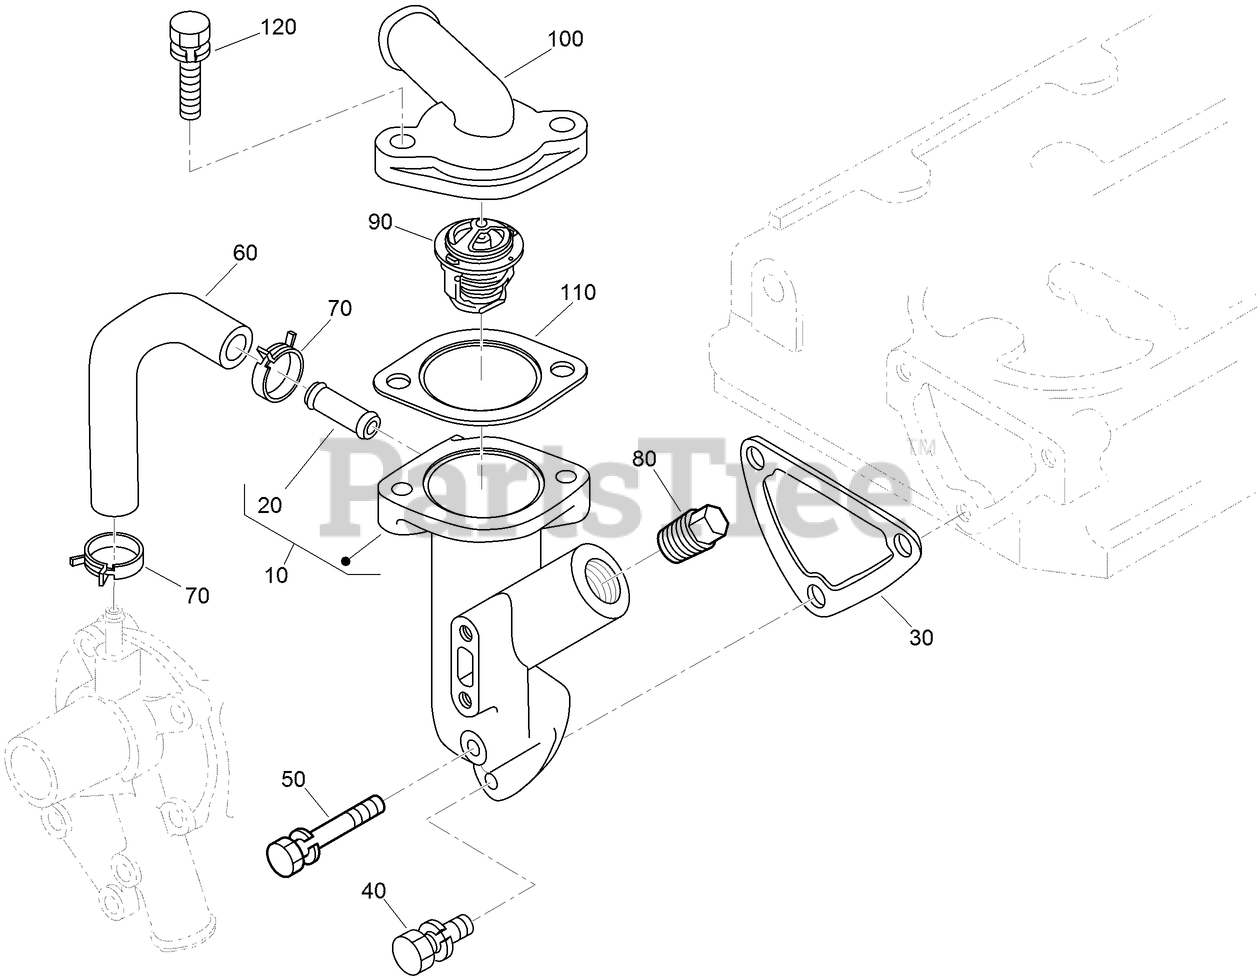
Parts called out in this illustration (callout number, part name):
10	WATER FLANGE ASM
20	PIPE-RETURN, WATER
30	GASKET-FLANGE, WATER
50	BOLT-SEMS
60	PIPE-RETURN, WATER
70	CLAMP-HOSE
90	THERMOSTAT ASM
100	COVER-THERMOSTAT
110	GASKET-THERMOSTAT
